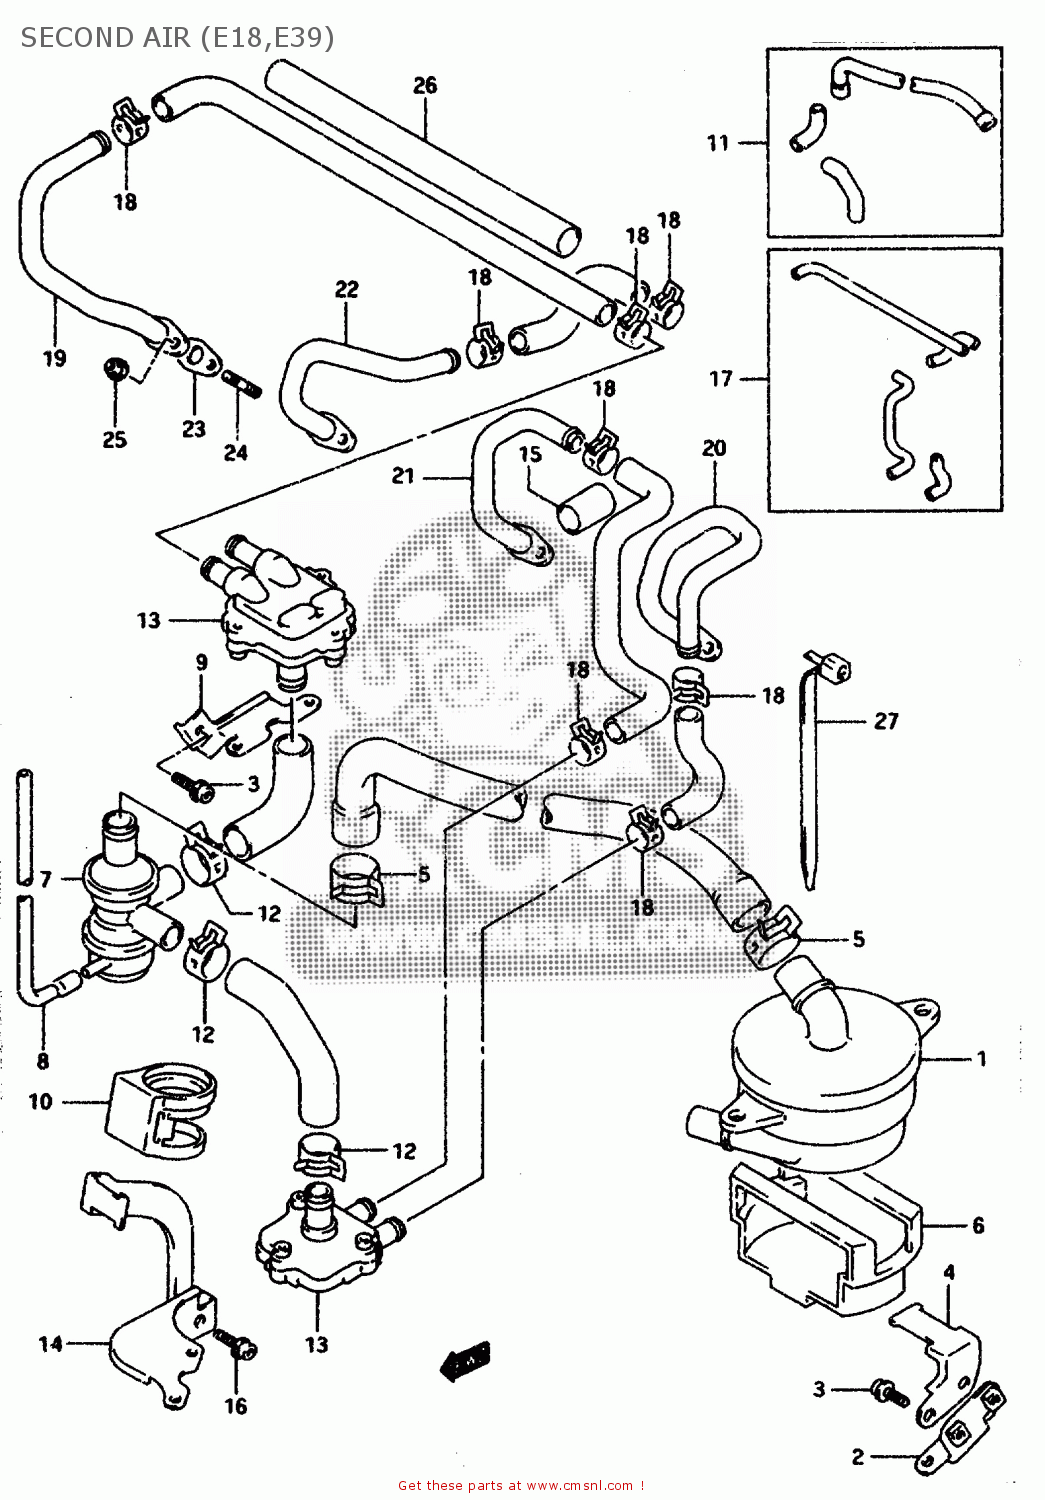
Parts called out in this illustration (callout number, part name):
1	CLEANER ASSEMBLY,SECOND AIR
2	BRACKET,SECOND AIR CLEANER
3	BOLT
4	BRACKET,SECOND AIR CLEANER
5	CLIP
6	CUSHION,SECOND AIR CLEANER
7	VALVE ASSEMBLY,SECOND AIR SWITCH
8	HOSE(4.5X8.5X600)
9	BRACKET,SECOND AIR REED VALVE
10	CUSHION,2ND AIR VALVE
11	HOSE SET,SECOND AIR NO.2
12	CLIP
13	VALVE ASSY,2ND AIR REED
14	BRACKET,SECOND AIR VALVE
15	PROTECTOR,REED VALVE
16	BOLT
17	HOSE SET,SECOND AIR NO.1
18	CLIP
19	PIPE,2ND AIR NO.4
20	PIPE,2ND AIR NO.1
21	PIPE,2ND AIR NO.2
22	PIPE COMP,SECOND AIR NO.3
23	GASKET,SECOND AIR PIPE (N (NAS)
24	STUD 6X16
25	NUT
26	PROTECTOR,REED VALVE H
27	CLAMP(L:165)
35	HOSE,RESERVOIR TANK INLET
36	CLIP
37	HOSE,RESERVOIR TANK OVERFLOW
38	CLAMP
39	CLAMP(L:165)
40	MOLDING,FUEL TANK RR
